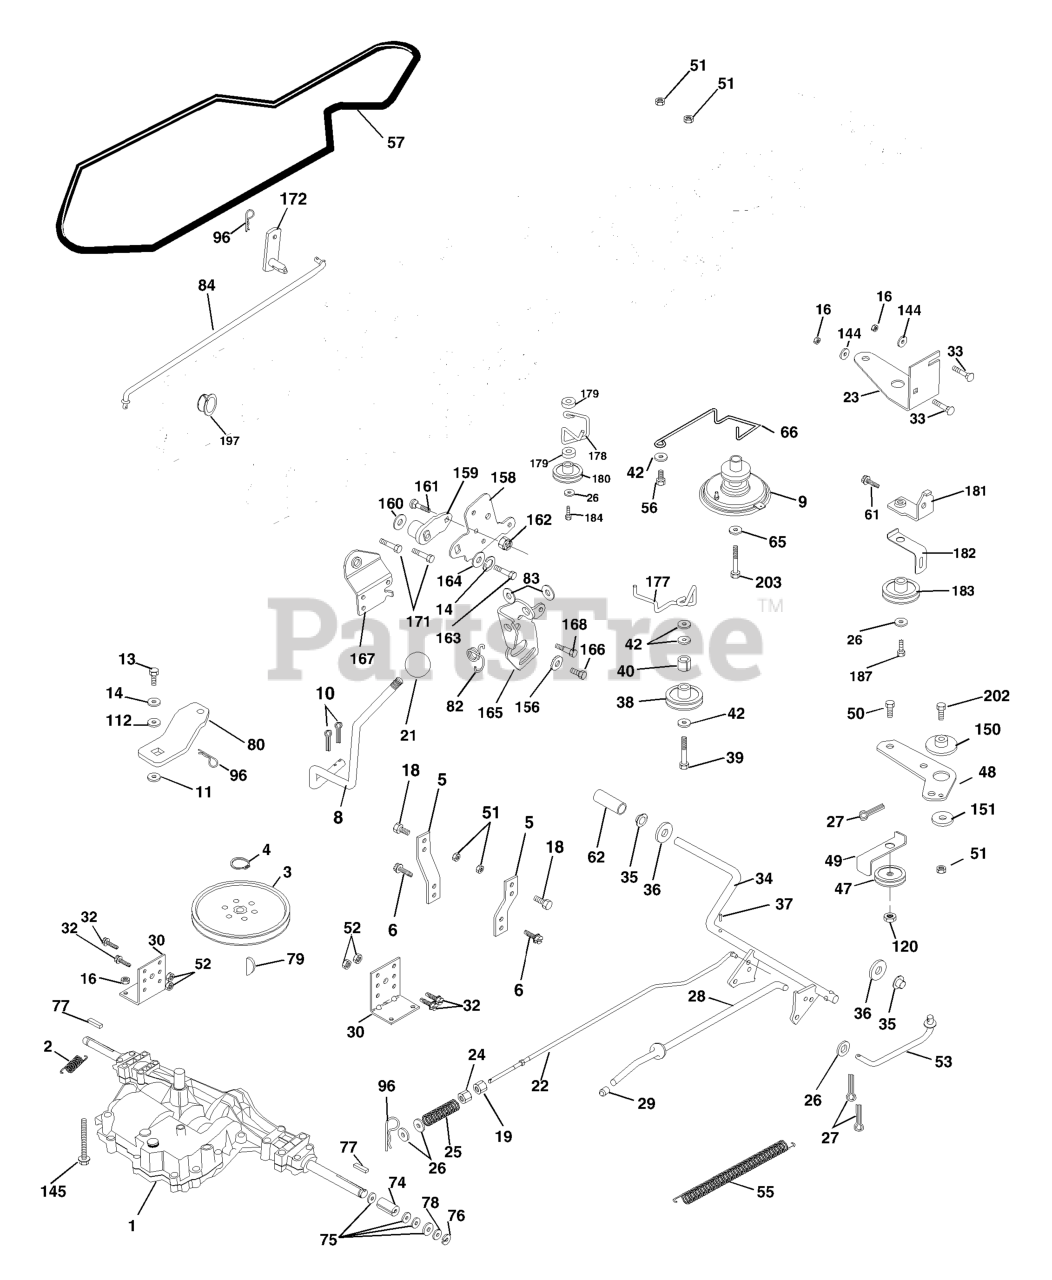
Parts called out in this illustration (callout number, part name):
2	SPRING,BRAKE RETURN
3	PULLEY
4	RETAINING RING LT
5	STRAP TORQUE
8	ROD.SHIFT.FENDER.ADJ.LT.CRD
9	CLUTCH ASSY
10	PIN COTTER
11	WASH-SHFT PLT LT
13	BOLT 1/4-28X3/4
14	LOCKWASHER
16	NUT.71038.31-18.HEX.NYLOCK
18	BOLT
19	NUT
21	KNOB.DUCKHEAD.1/2
23	Bracket Clutch Noram
24	NUT
25	SPRING ROD LT
26	WASHER
27	COTTER PIN
28	ROD BRAKE PARK LT
29	PLUNGER CAP
30	BRKT, MOUNT TRNSAXLE
32	BOLT
33	RP BOLT 5/16-18 X3/4 ZN/YEL GR
35	BEARING.NYLON
36	WASHER LT
37	DRIVE PIN
38	PULLEY.FLAT
42	WASHER
47	IDLER PULLEY
48	BELLCRANK, CLUTCH
49	RETAIN BELT
50	BOLT
52	LOCKNUT
53	LINK, CLUTCH LT
55	SPRING, RETURN LT
57	V-BELT.KEV.111"
61	SCREW 3/8-16X3/4
62	COVER, PEDAL (1 2)
65	LOCKWASHER
66	KEEPER BELT ENGINE
74	SPACER AXLE
77	SQUARE KEY
79	KEY STD (1373) DANA
82	SPRING,TORSION
83	WASHER
96	RETAINER M
112	WASHER LT
144	Washer 11/32 x 5/8 x 16 Ga.
145	BOLT
150	BUSHING.BELLCRANK.GRD.DR
151	WASHER 12/32X2X10GA
153	BOLT RB
156	WASHER.SRRTD.5/16
158	BRACKET
159	HUB
160	Washer 29/32 x 1-1/4 x 16 Ga.
161	BOLT
162	NUT.CROWNLOCK.1/4
163	BOLT
164	Washer 5/8 x .281 x 10 Ga.
165	RP BRACKET
167	BRACKET.SUPT.SHIFT.CRD
168	BOLT.SHOULDER.5/16-18X
171	SCREW LT
172	SHAFT
180	PULLEY.FLAT.IDLER
181	BRKT.IDLER.GRD.DR.CRD
182	KEEPER BELT
183	PULLEY.V-IDLER
184	SCREW.HXWSH.3/8
187	SCREW
202	BOLT.3/8-16X1.50
203	BOLT.HEX.7/16-20 X 5
